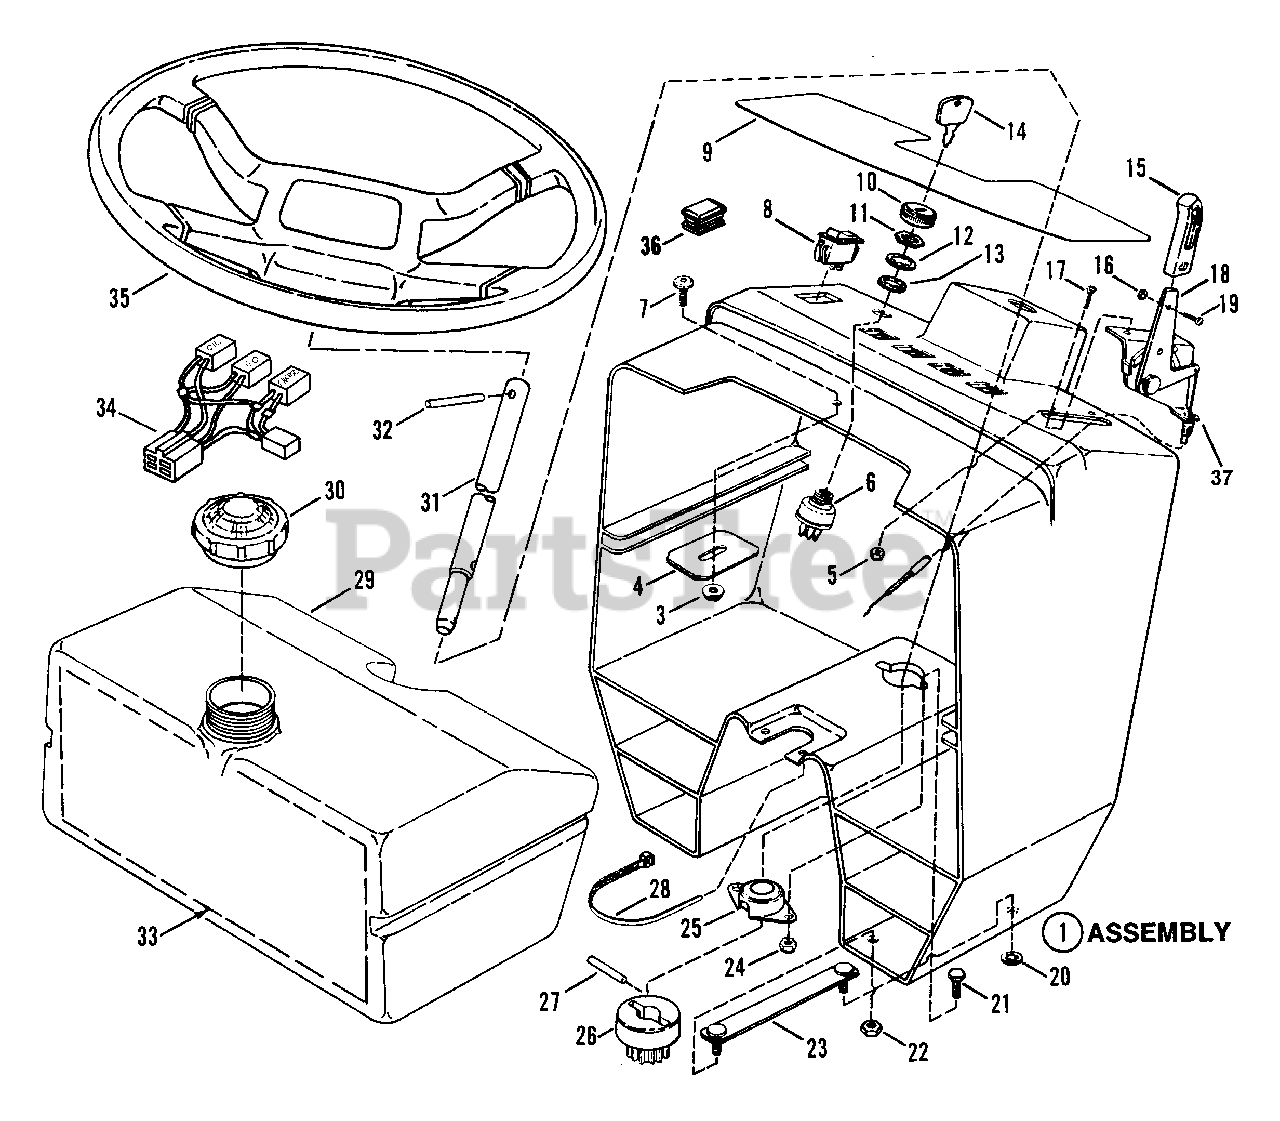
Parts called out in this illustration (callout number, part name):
1	ASSEMBLY, Console
1	CONSOLE
3	NUT, 5/16-18 Hex Flange Lock
4	BRACKET, Hood Latch Catch
5	NUT, #10-24 Hex Nyloc
6	KEYSWITCH
7	SCREW, 5/16-18 x 7/8" Torx, Truss Hd.
8	SWITCH, Headlights
9	DECAL, Console
10	BEZEL
11	NUT, 5/8-32 Hex
12	WASHER, 5/8 Internal Tooth Lock
13	SPACER
14	KEY (With Cover)
15	HANDLE, Throttle Control
16	NUT, #8-32 Hex
17	SCREW, #10-24 x 5/8" Machine
18	CONTROL, Throttle 44.6" Long
18	CONTROL, Throttle 38.0" Long
19	SCREW, 18-32 x 3/8" Cross-Recessed, Fillester Head
20	RETAINER
21	SCREW, 1/4-20 x 3/4" H.H.C.
22	NUT, 5/16-18 Hex Center Lock
23	ASSEMBLY, Strap-Clinch Stud
24	NUT, 1/4-20 Hex Nyloc
25	ASSEMBLY, Flange Bearing
26	GEAR, Pinion, Steering Shaft
27	PIN, Dowel, 1/4 x 1 1/4"
28	TIE, Wire
29	ASSM'Y., Fuel Tank
30	CAP, Fuel Tank
31	SHAFT, Steering
32	ROLL-PIN
33	HEAT SHIELD
34	HARNESS, Wiring, Indicator Lights
35	STEERING WHEEL
36	LENS, Indicator Lights
37	CONTROL, Throttle
